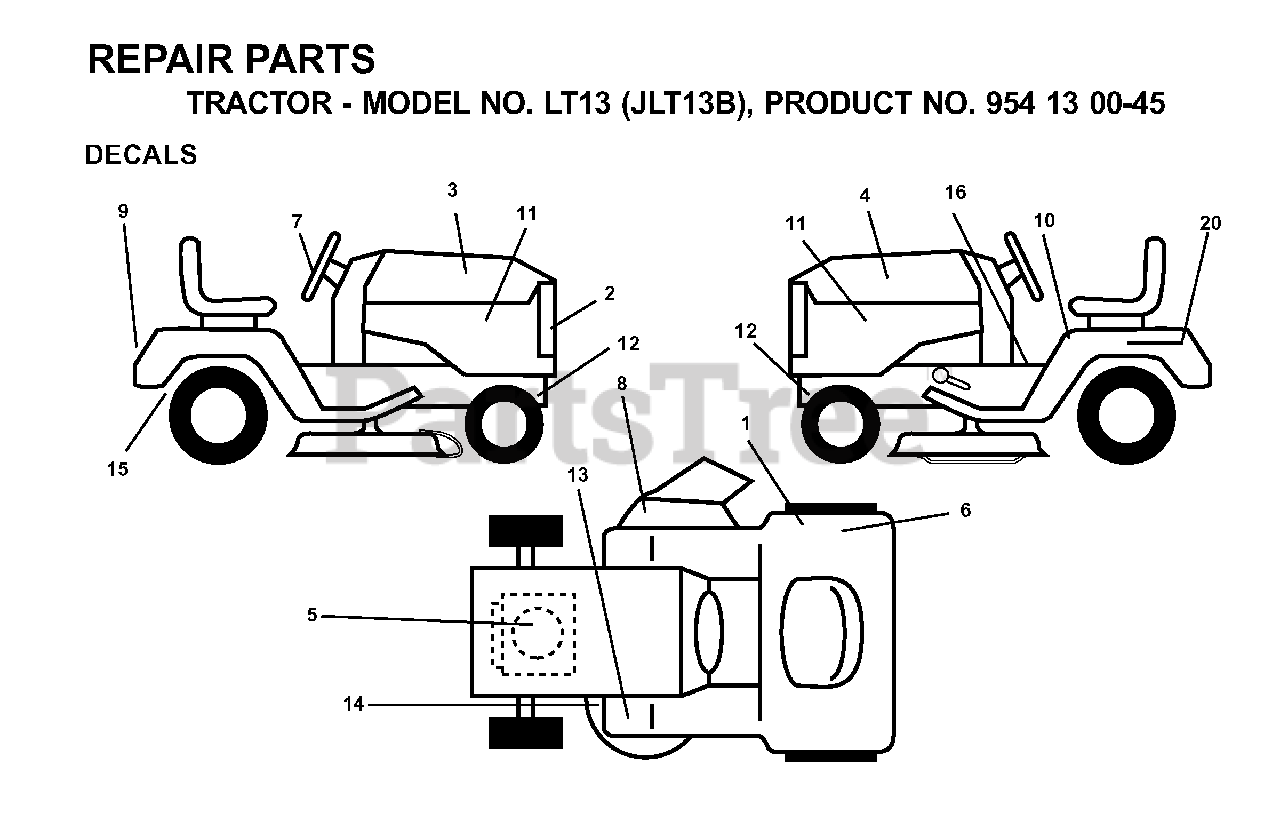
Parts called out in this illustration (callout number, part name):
1	DECAL CERTIFICATION
5	DECAL HP ENGINE
6	DECAL EUROPE STANDARD CE
8	DECAL MOWER CUT/FINGER
10	DECAL READ OWNER'S MAN SYMS
14	DECAL V-BELT SCHEMATIC
16	DECAL PARK BRAKE
20	DECAL BTRY SYMBOLS
